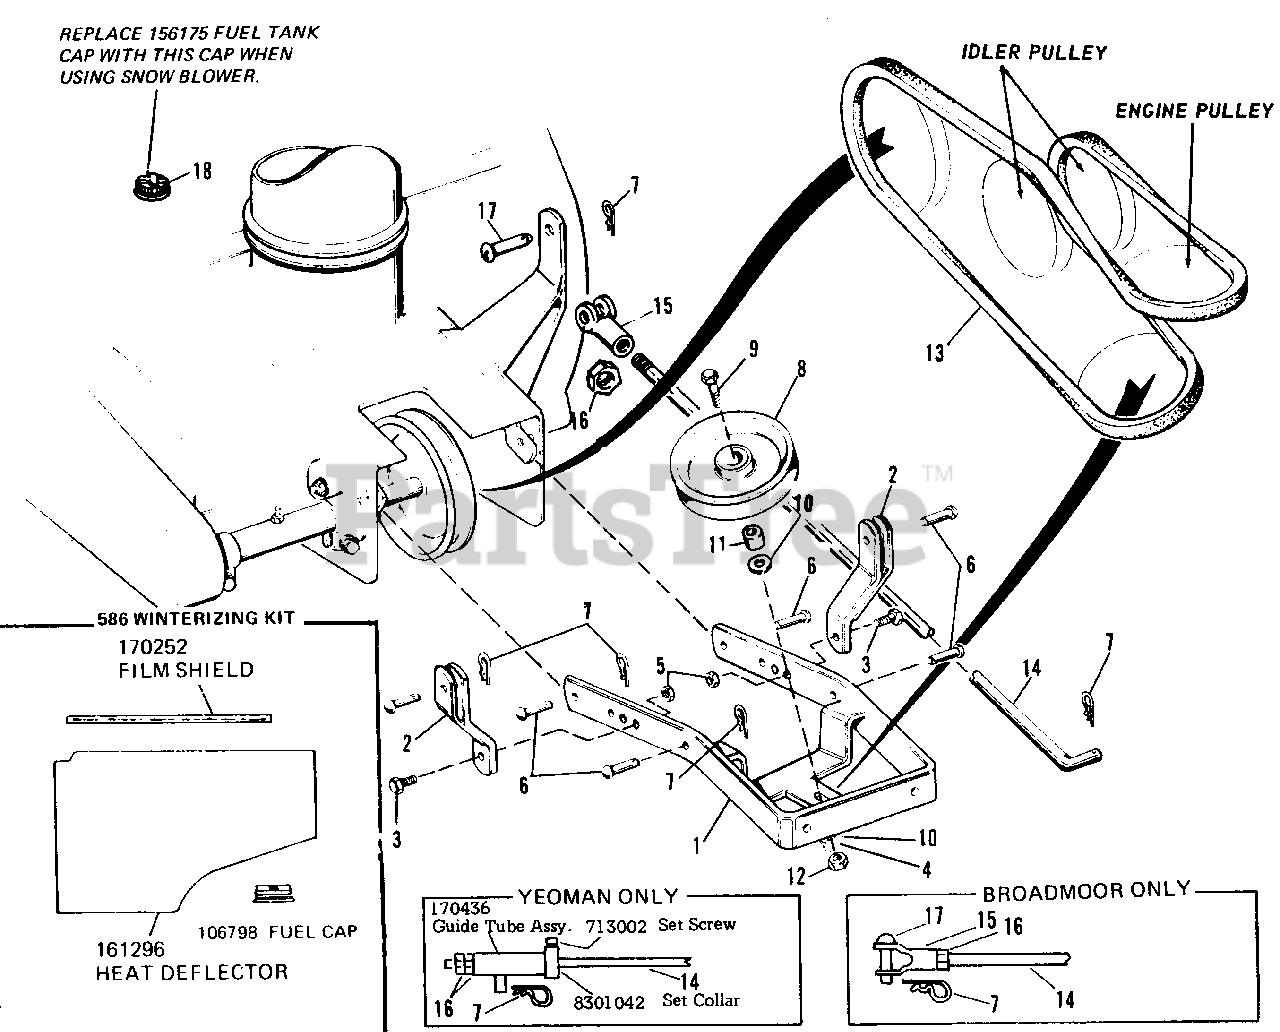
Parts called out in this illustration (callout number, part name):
1	Push Arm Assembly
2	Support Arm Assembly
3	Hex Capscrew, 3/8"-16 x 1" lg.
4	Lock Washer, 3/8"
5	Hex Nut, Full Lock 3/8"-16
7	Spring Clip
9	Hex Capscrew 3/8"-16 x 1-3/4" lg.
10	Plain Washer 3/8"
12	Hex Nut, Full 3/8"-16
14	Front Lift Rod
15	Adjusting Yoke
16	Hex Nut, Full 1/2"-20
18	Cap (Winter) Fuel Tank
19	Deflector-Heat
20	Film-Shield
20	Decal, Safety
20	Serial Number Plate
